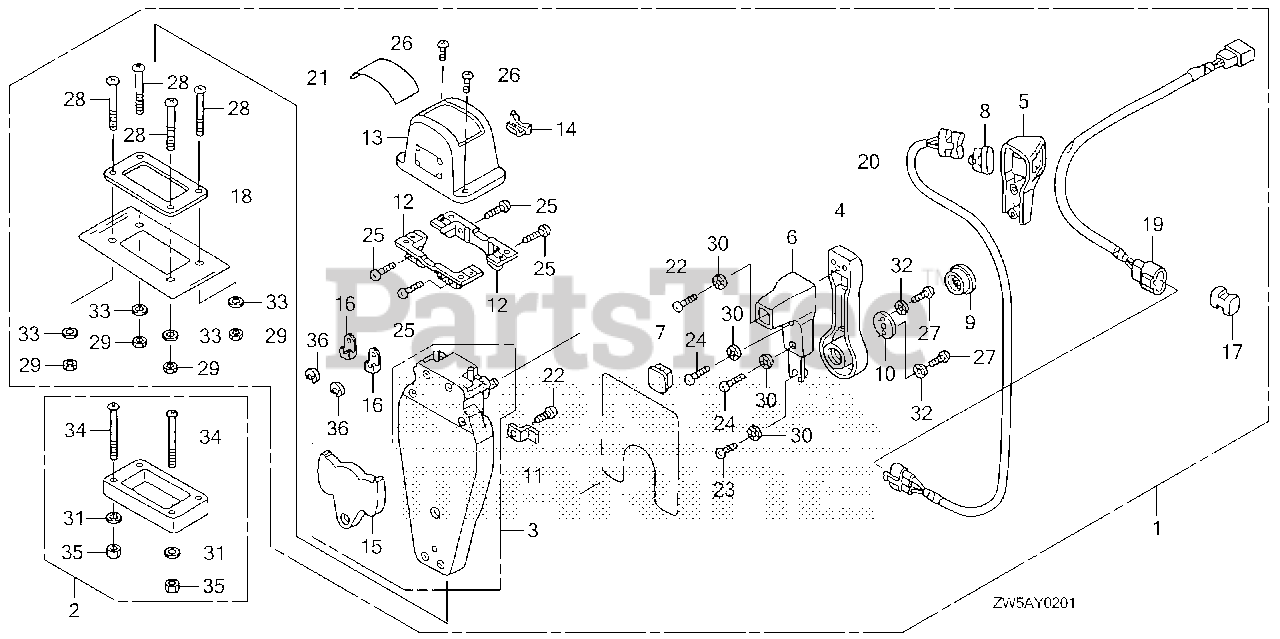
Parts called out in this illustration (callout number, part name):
1	BOX KIT, REMOTE CONTROL (TOP MOUNT SINGLE)(L)
2	SPACER KIT, REMOTE CONTROL BOX (TOP MOUNT SINGLE)
3	HOUSING ASSY., R. (INNER) (TOP MOUNT)
4	HANDLE, REMOTE CONTROL
5	COVER, R. GRIP
6	GRIP, REMOTE CONTROL HANDLE
7	CAP, GRIP
8	CAP, SWITCH
9	BUTTON, THROTTLE
10	PLATE, HANDLE
11	PLATE, CABLE CLAMP
12	BRACKET, REMOTE CONTROL HOUSING
13	HOUSING, REMOTE CONTROL BOX
14	HOUSING, LEAD
15	PLATE, DWELL
16	TERMINAL, CABLE
17	SPACER, CABLE CLAMP
18	GASKET, SINGLE
19	SUB-HARNESS ASSY., POWER TRIM-TILT (B)
20	SWITCH ASSY., POWER TRIM-TILT (B)
21	MARK, REMOTE CONTROL (SINGLE)
22	SCREW, PAN (5X16)
23	SCREW, PAN (5X10)
24	SCREW, PAN (5X20)
25	SCREW, PAN (5X18)
26	SCREW, PAN (4X10)
27	SCREW, PAN (6X18)
28	SCREW, PAN (5X40)
29	NUT, HEX. (5MM)
30	WASHER, LOCK (5MM)
31	WASHER, PLAIN (5MM)
32	WASHER, LOCK (6MM)
33	WASHER, PLAIN (5MM)
34	SCREW, PAN (5X65)
35	NUT, HEX. (5MM)
36	E-RING (6MM)
